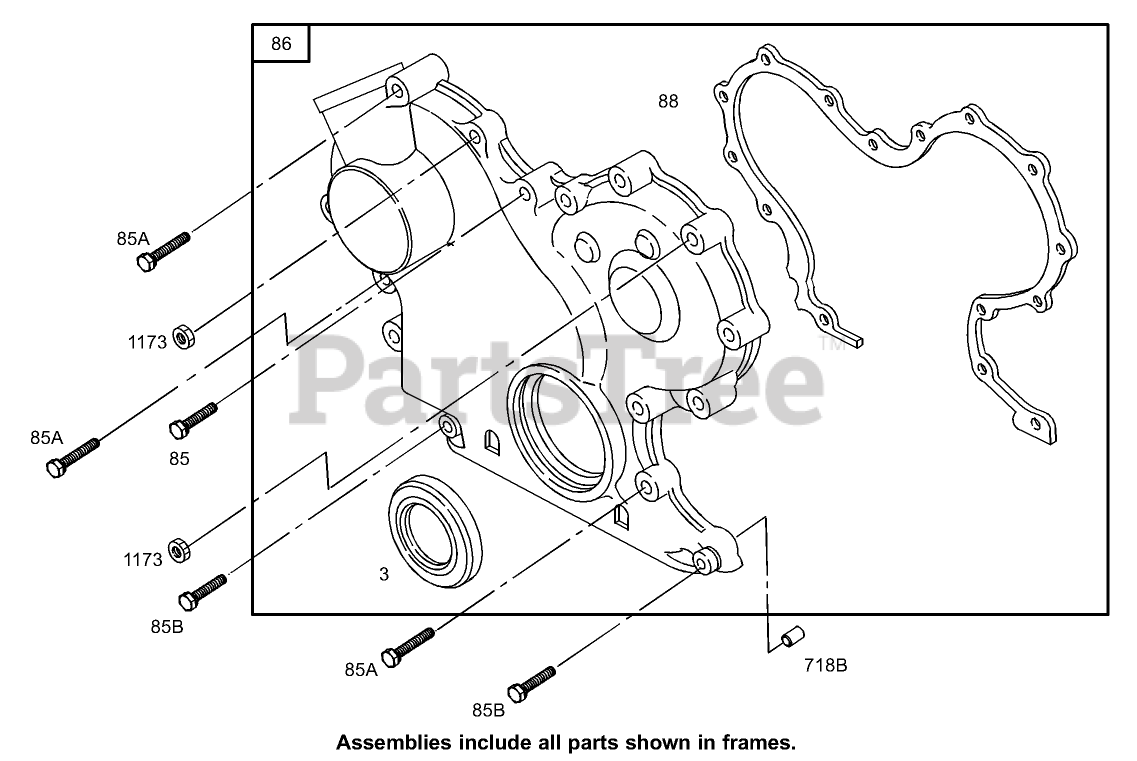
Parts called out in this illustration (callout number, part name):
3	OBS SEAL-OIL
85	SCREW-HEX
85A	SCREW-HEX
85B	SCREW-HEX
86	GEAR COVER ASM
88	GASKET-COVER, GEAR
718B	PIN-LOCATING
1173	NUT-HEX, METRIC
